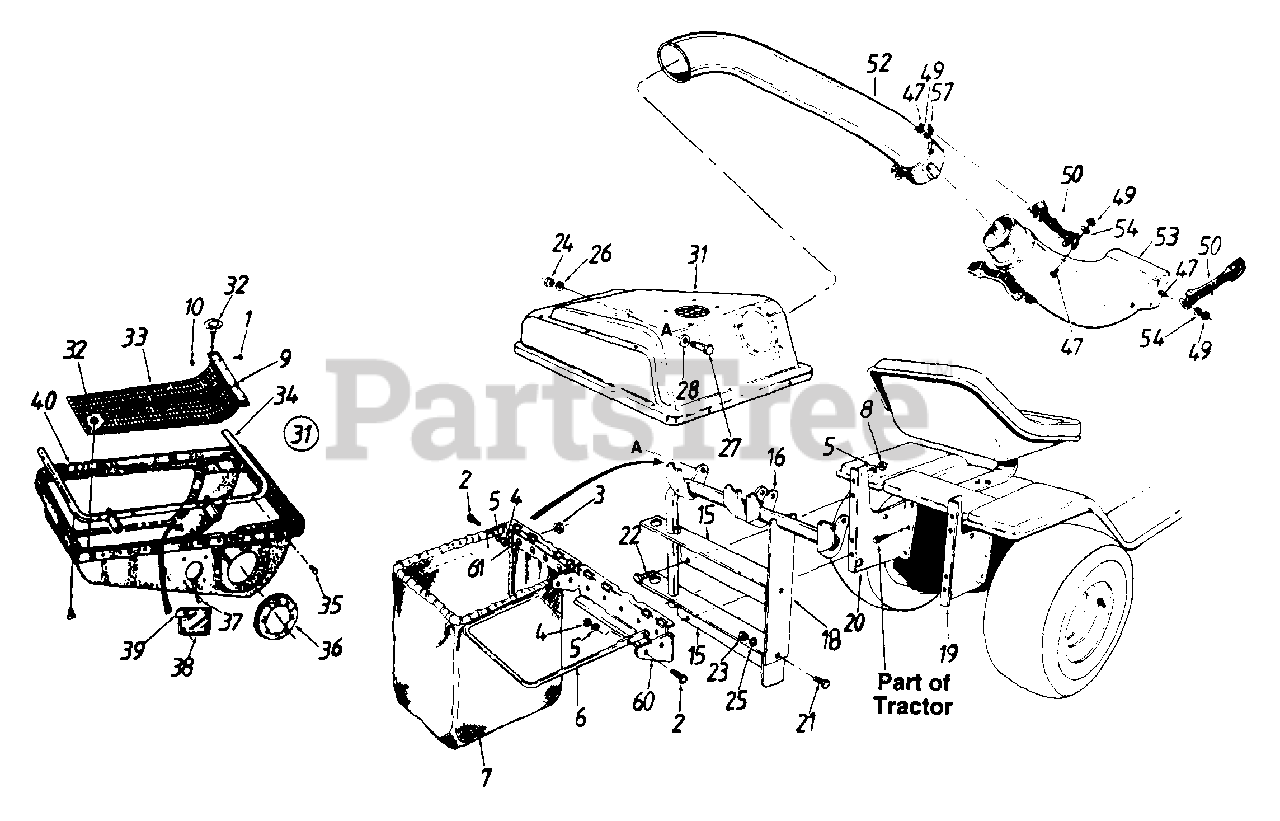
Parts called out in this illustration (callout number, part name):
1	Pop Rivet .188 Dia.
2	Hex Bolt 1/4-28 x .75"
3	Hex Sems Nut #10-24 Thd.
4	Hex Nut 1/4-28 Thd.
5	L-Wash. 1/4" I.D.
6	Catcher Bag Frame
7	Grass Catcher Bag
8	Hex Nut 1/4-20 Thd.
9	Screen Mtg. Brkt.
10	Flat Wash. 1/4" I.D.
15	Catcher Support Tube Mtg. Brkt.
16	Catcher Support Tube Ass'y.
18	Catcher Latch and Support Brkt.
19	Grass Catcher Support Brkt. - R.H.
20	Grass Catcher Support Brkt. - L.H.
21	Hex Bolt 5/16-18 x .75"
22	Hex Bolt 1/4-20 x .62" Lg. - Grade 5
23	Hex Nut 5/16-18 Thd.
24	Hex Nut 3/8-16 Thd.
25	L-Wash. 5/16" I.D.
26	L-Wash. 3/8" I.D.
27	Shld. Bolt 3/8-16 x .50" Dia.
28	Bell-Wash. .505" I.D. x 1.0" O.D.
31	Grass Catcher Cover Ass'y.
32	Twist Fastener
33	Screen
34	Hinge Brkt. Ass'y.
35	Hex AB-Tap Scr. 1/4 x .62"
37	Truss Mach. B-Tap Scr. #10 x .5" Lg.
38	Plastic Plate
39	Speed Nut
40	Grass Catcher Cover
47	Hex Bolt 1/4-20 x .5"
49	Hex Ins. L-Nut 1/4-20 Thd.
50	Retainer Strap Ass'y.
52	Catcher Tube
53	Discharge Chute
54	L-Wash. .27" I.D.
57	Retainer Hook Brkt.
60	Bag Frame Hanger Brkt.
61	Truss Mach. Scr. #10-24 x .5" Lg.
